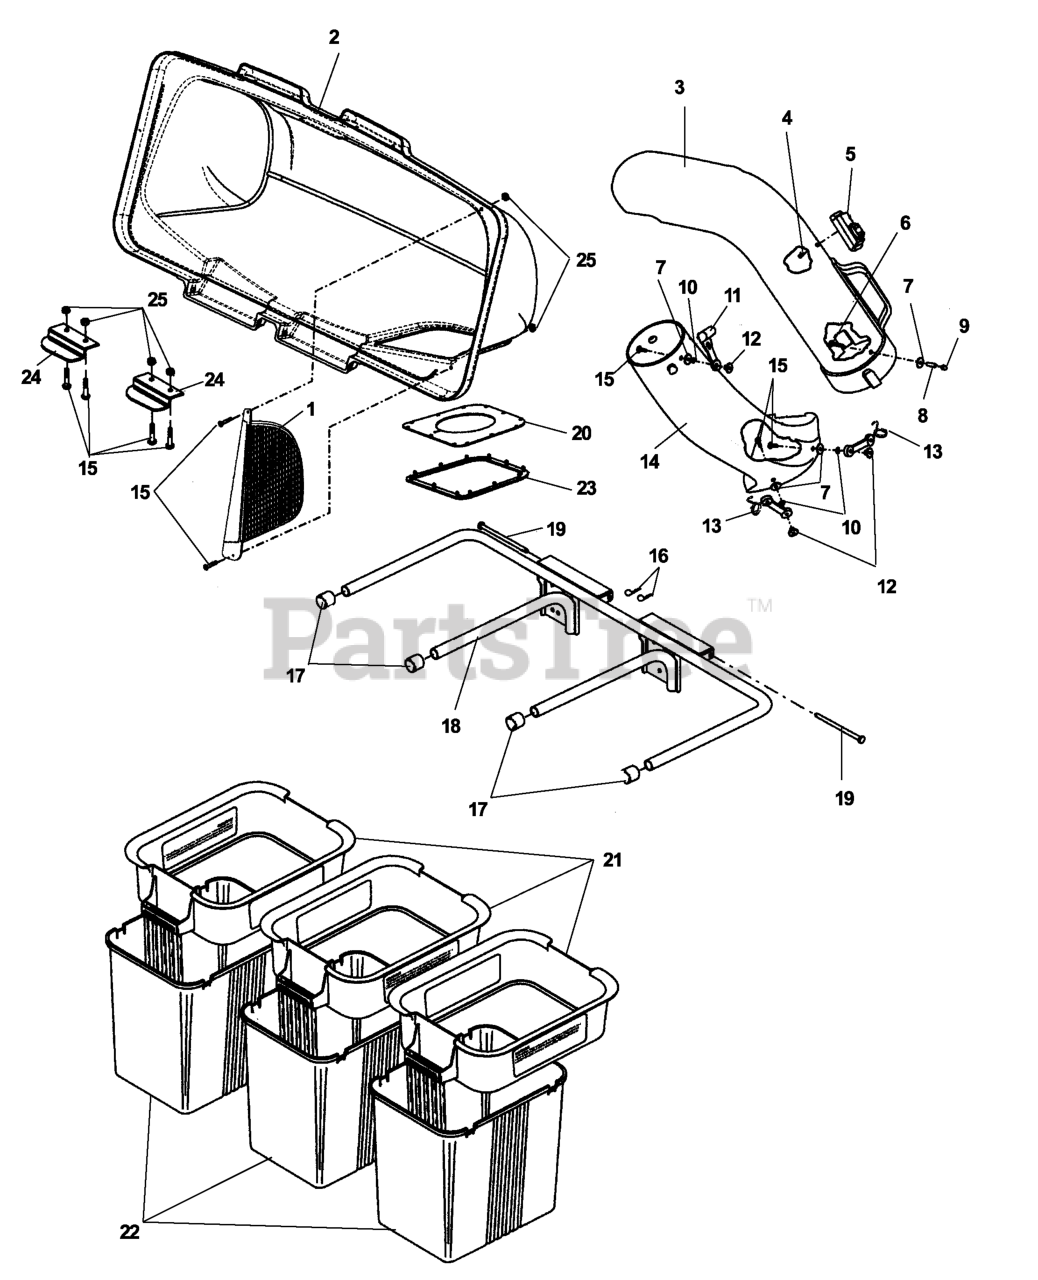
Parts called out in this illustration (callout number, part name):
1	SCREEN.COVER.BAGGER
2	COVER.ASM.3BIN.GENERIC.
3	CHUTE.COLLECTION.UPPER
4	SCREW
5	DUMP BAG INDICATOR
6	SCREW #10-24 X 1-1/8 ZD SPEC
8	BSHG .202X.75 LG SPLIT ZD SPEC
9	NUT 10-24 ACORN ZD
10	WASHER - 3/16 LOCK ZD
11	HOOD LATCH
12	NUT 10-24 WELD PLATED
13	LATCH ASSY TBR
14	CHUTE, LOWER 54
15	SCREW #10-24 X 5/8
16	RETAINER SPRING
17	TUBING PLUG
18	BAGGER, FRAME
19	BAGGER.HINGE.PIN
20	SEAL.BAGGER.TOP.3-BIN.BLK
21	CONTAINER TOP
22	CONTAINER BOTTOM
23	GASKET.COVER.BAGGER
24	LATCH CER38
25	NUT 10-24 NYLOC
